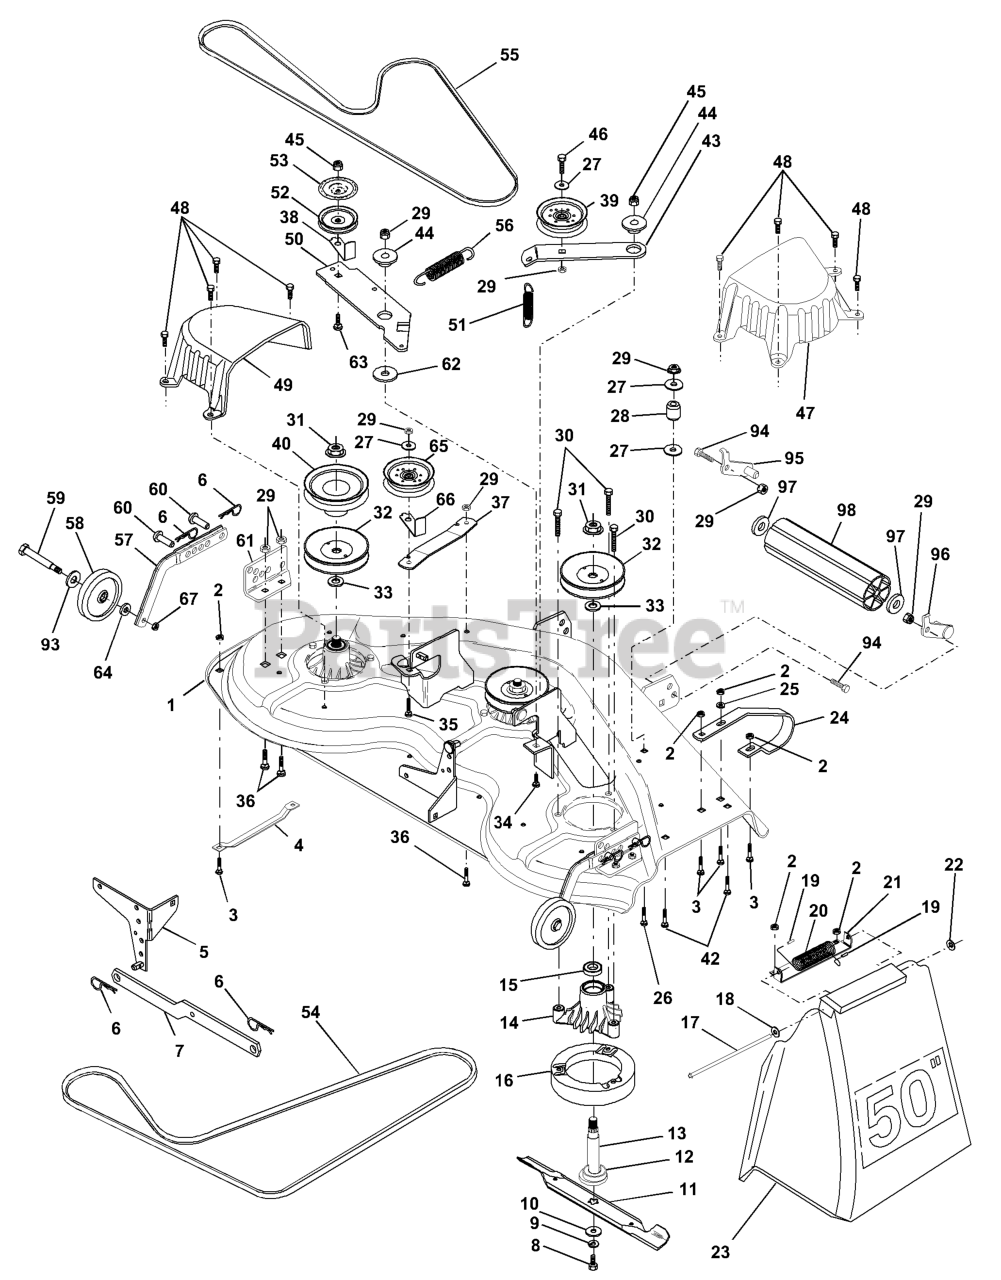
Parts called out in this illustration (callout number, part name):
1	DECK ASM MWR 50VT
2	NUT.71038.31-18.HEX.NYLOCK
3	BOLT.CARR.SQNK.5/16-18UNC.X3/4
4	RUNNER-LH M
5	BRACKET SWAY BAR
6	RETAINER-SPRNG RB
7	REAR SUSP ARM
8	BLADE BOLT
9	LOCKWASHER
10	WASHER.BLADE
11	BLADE.50".HI-LIFT
12	BEARING.BALL.#6204.(MANDREL)
13	SHAFT.ASM.W/BEARING
14	HOUSING.MANDREL.44/46" VENT
16	STRIPPER
17	ROD-HINGE T
18	Washer 11/32 x 5/8 x 16 Ga.
19	CAP-SLEEVE LT
20	SPRING TORSION
21	BRACKET, DEFLECTOR
22	NUT PUSH M
23	SHIELD.DEFLECTOR.MOWER.50"BLK.
25	WASHER M
27	WASHER
28	IDLER SPRING SPACER
29	NUT
30	SCREW
31	NUT
32	MANDREL PULLEY
33	WASHER
34	BOLT.3/8-14X1.25
35	BOLT
36	BOLT D
37	STIFFENER ARM
38	KEEPER
39	FLAT IDLER PULLEY
40	PULLEY.DRIVEN.44"
42	RP BOLT 5/16-18 X3/4 ZN/YEL GR
43	ARM.IDLER.SEC.44"
44	SPACER RETAINER
46	BOLT
47	COVER MANDRELL
48	SCREW.1/4-20X5/8
49	COVER.MANDREL.LH.44"
50	ARM.IDLER.PRIMARY
51	SPRING.SEC.44"VEN
52	PULLEY IDLER
53	SHIELD IDLER
54	V-BELT.PRMRY 46/50 VENT.BLK BK
55	BELT, V GROUND DRIVE 95 25
57	BAR.ASM.GUAGE.WHEEL
58	WHEEL.GAUGE.BLK.4.93
59	BOLT M
60	PIN.CLEVIS
61	BRACKET.GUAGE.WHEEL
62	HARDENED WASHER
63	BOLT.3/8-16X1.50
64	WASHER.5/16.FLAT.STE.STD.
65	IDLER-FLAT T
66	KEEPER
67	LOCKNUT
95	BRACKET LH (A)
96	BRACKET RH (B)
97	Washer 17/32 x 7/8 x 16 Ga.
98	NOSE ROLLER
99	BOLT
100	Washer 17/32 x 15/16 x 12 Ga.
